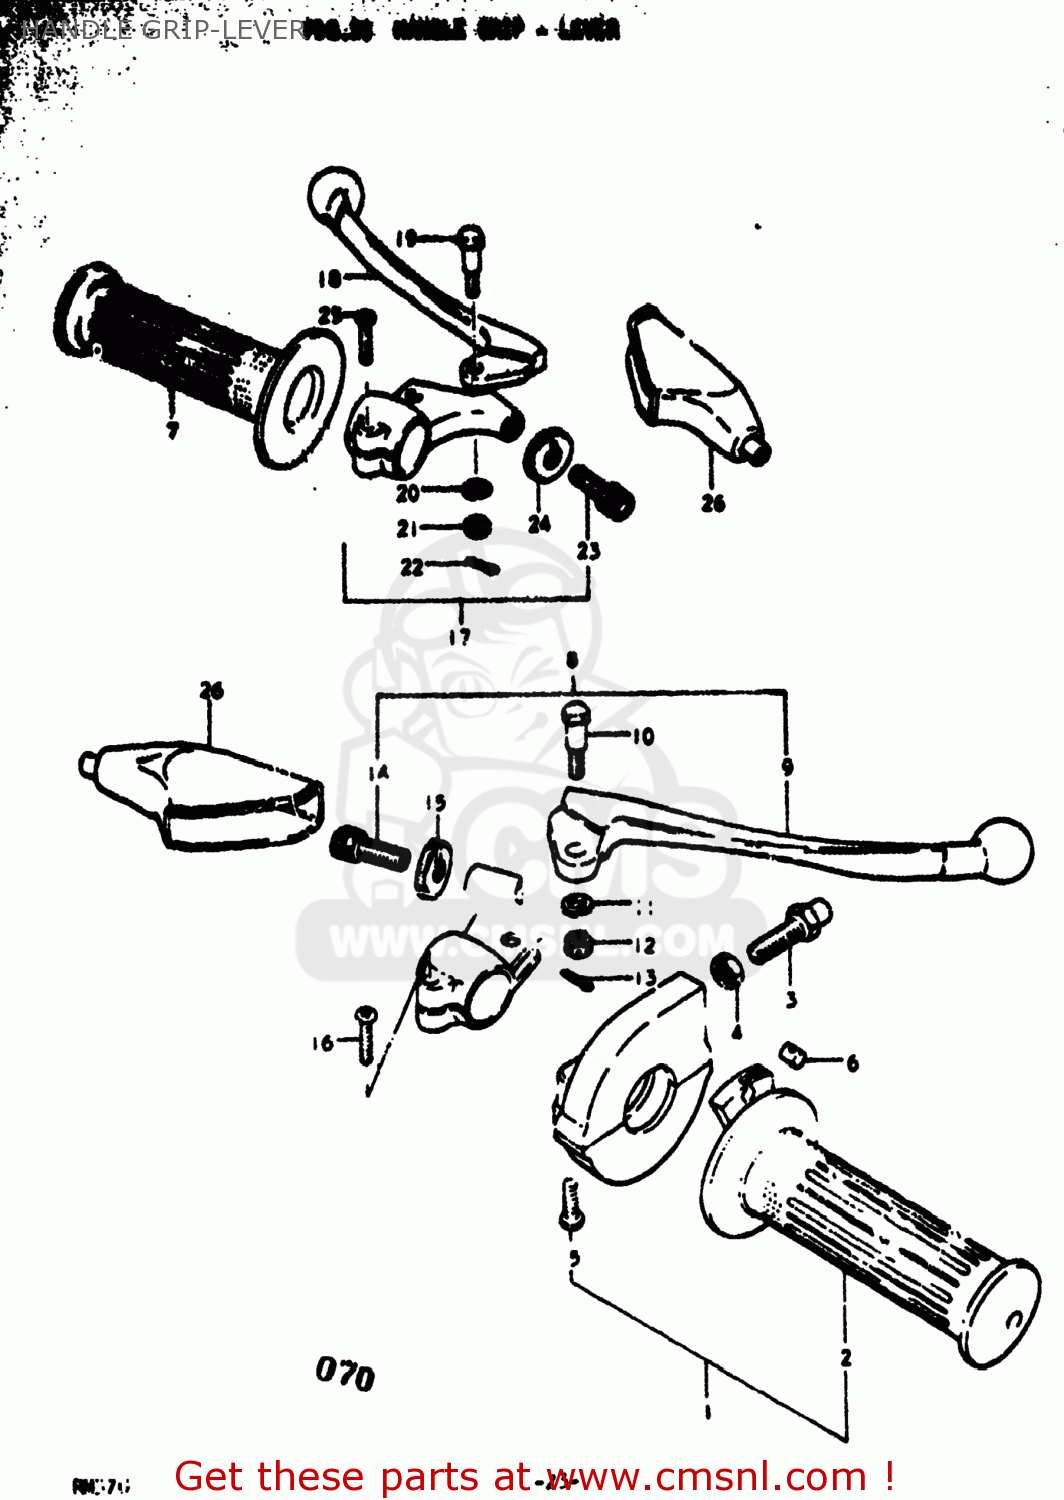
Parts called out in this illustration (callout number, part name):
1	CASE ASSEMBLY,THROTTLE
2	GRIP,THROTTLE
4	NUT
5	SCREW
6	PIECE,THROTTLE END
7	GRIP,LEFT
8	LEVER ASSEMBLY,BRAKE
9	LEVER,BRAKE
10	BOLT,LEVER
11	LOCK WASHER
12	NUT,LEVER FITTNG
13	COTTER PIN
14	ADJUSTER,CABLE
15	NUT,CABLE ADJUSTER
16	SCREW
17	LEVER ASSEMBLY
18	LEVER,CLUTCH
19	BOLT,LEVER
20	LOCK WASHER
21	NUT,LEVER FITTNG
22	COTTER PIN
23	ADJUSTER,CABLE
24	NUT,CABLE ADJUSTER
25	SCREW
26	COVER,CLUTCH LEVER
